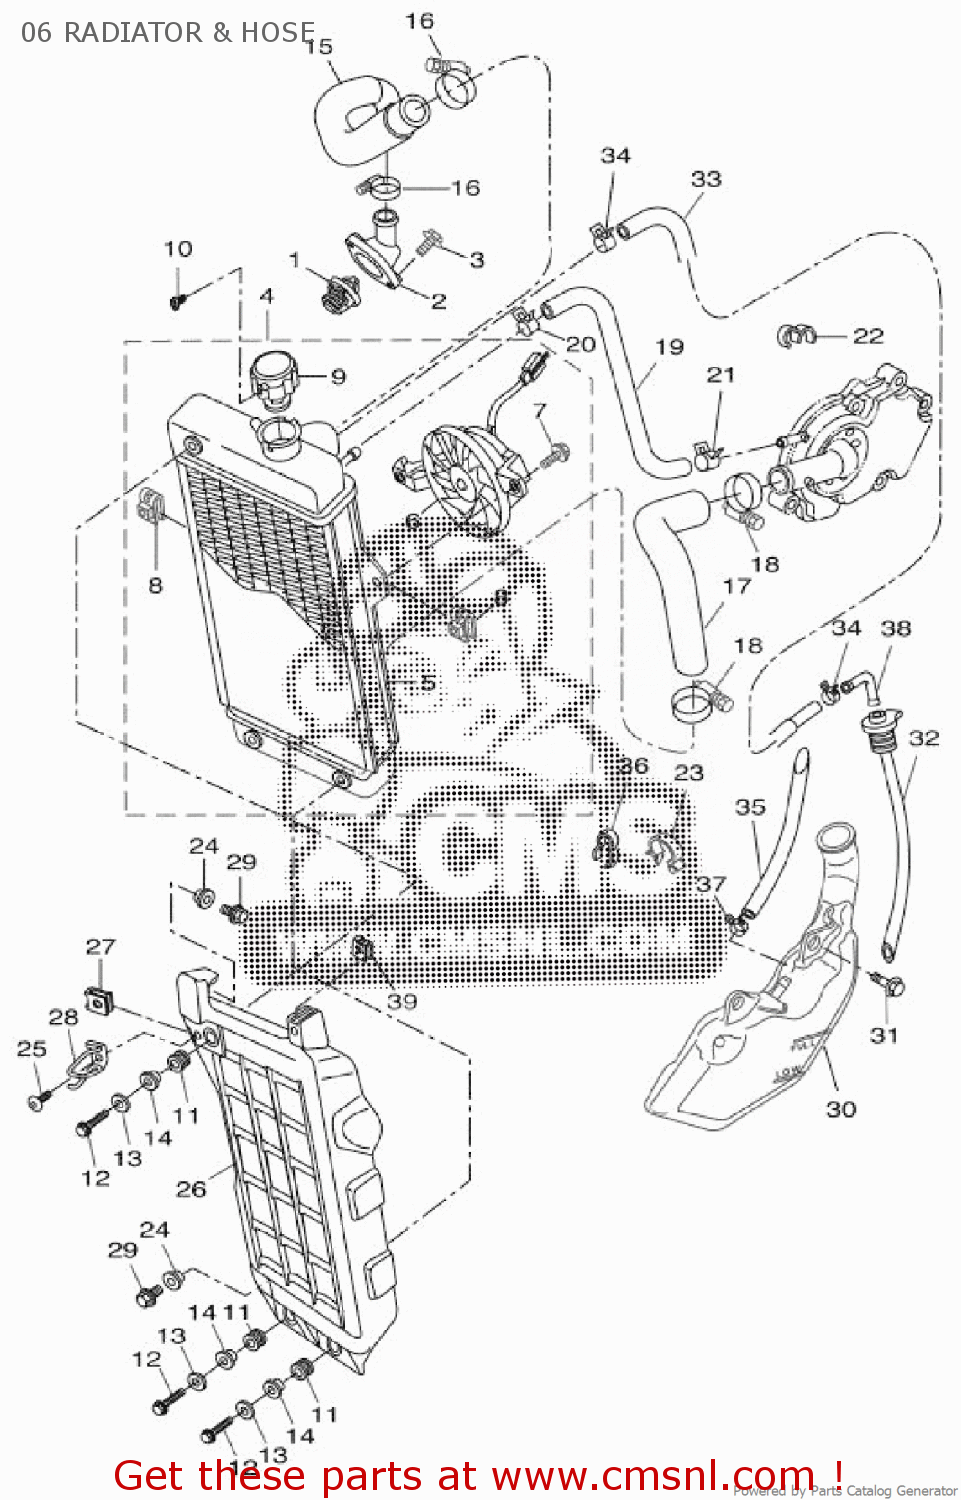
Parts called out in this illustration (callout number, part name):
1	THERMOSTAT
2	COVER, THERMOSTAT
3	BOLT, FLANGE
4	RADIATOR ASSY
5	RADIATEUR COMPLET
6	BLOWER ASSY
7	BOLT, BLOWER HOLDI
8	NUT 1
9	CAP, RADIATOR
10	BOLT, SOCKET
11	GROMMET (4L0)
12	BOLT(4MY)
13	WASHER(6TA)
14	COLLAR
15	HOSE 3
16	HOSE CLAMP ASSY
17	HOSE 4
18	HOSE CLAMP ASSY
19	HOSE
20	CLIP (26H)
21	CLIP (26H)
22	CLAMP(6M7)
23	CLAMP
24	ENTRETOISE
25	BOLT HEX
26	BRACKET 1
27	NUT, SPRING
28	HOLDER WIRE
29	BOLT, FLANGE
30	TANK RECOVERY
31	BOLT
32	CAP
33	PIPE BREATHER
34	CLIP (26H)
35	PIPE OVERFLOW
36	CLAMP(53Y)
37	CLIP (26H)
38	ELBOW
39	NUT, SPRING
